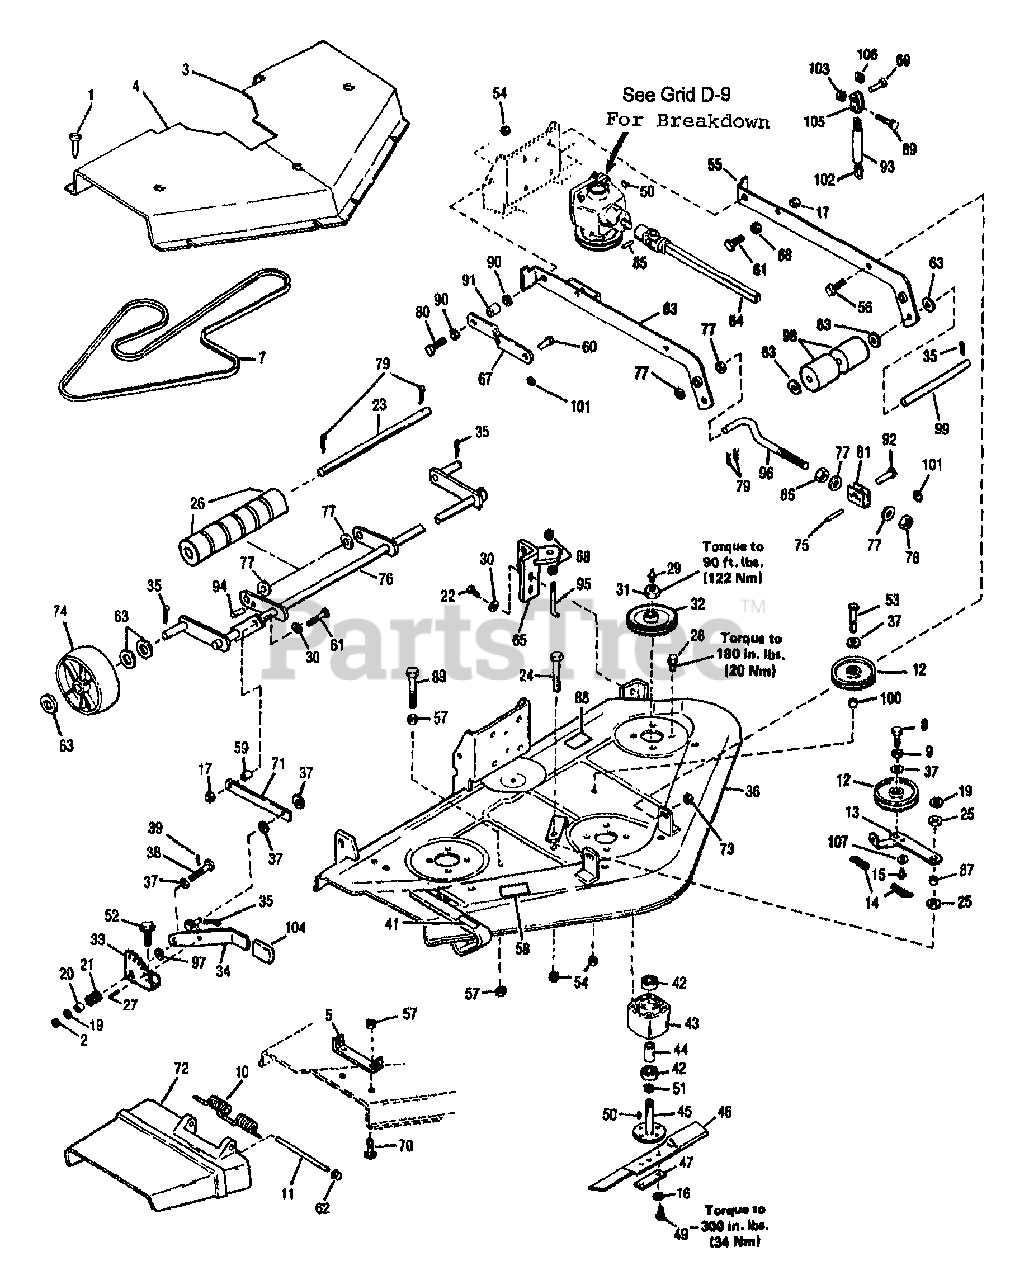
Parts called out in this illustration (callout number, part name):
5	BRKT-HINGE
8	SCR-HH 1/4-20X1.25 G5 ZP
9	WASHER-LK .5
10	SPRING-TORSION
12	PULLEY-IDLER
14	SPRING
15	BUTTON-WEAR
16	WASHER-LK .375 @ DEPL
17	NUT-LOCK 3/8-16
19	WASHER-1.06X.531X.1 ZP
20	SPACER-TUBULAR
21	SPRING
22	SCR-HH 3/8-16X1.0 G5 ZP
23	AXLE-ROLLER
24	SCR-HH 1/2-13X1.5 G5 ZP
25	WASHER
26	ROLLER
27	PIN-.312X.75
28	SCR-HFLK 5/16-18X.75
29	FITTING-GREASE 1/4-28X2.00
30	WASHER-FLAT 3/8 SAE
31	NUT-H/LK
32	SHEAVE-BLADE
34	ASSM-HANDLE
35	PIN-COTTER .120X1.00 ZP
36	BASE-MOWER W/DECALS
37	WASHER-FLAT .88X.5X.06 ZP
38	SCR-HH 1/2-13X2.5 SPECIAL
41	DECAL-CUTTING LINE
42	BEARING-BALL
43	HOUSING-SPINDLE
45	SHAFT
46	BLADE-CUTTER
47	PLATE
49	SCR-HH 3/8-24X1.0 G5 ZP
50	KEY-WOODRUFF .188X.75
51	WASHER-SPECIAL
52	SCR-HFLK 5/16-18X.75 ZP
53	SCR-HH 1/2-13X2.0 G5 ZP
54	NUT-TOP LOCK 1/2-13 ZP
55	ASSM-SUPPORT LH
56	SCR-HFLK 3/8-16X1.00 ZP
57	NUT-TOP/LK 5/16-18 ZP
58	DECAL-OPEI CAUTION
59	SPACER-.625X.39X.343
60	PIN-CLEVIS .625X1.44
61	SCR-HH 3/8-16X1.5 G5 ZP
62	NUT-PUSH 3/8 ZP
63	WASHER-1.305X.649X.098 ZP
65	ASSM-SUPT
68	NUT-HEX/JAM 3/8-16 ZP
69	PIN-CLEVIS
70	BOLT-CARR 5/16-18X.63 ZP
71	LINK-CONNECTING
72	DEFLECTOR-DISCHARGE
73	NUT-HFLK 3/8-16 ZP
74	WHEEL-GAGE
75	PIN-DRIVE
77	WASHER-1.38 X.765X .06 ZP
78	NUT .750-10
79	PIN-COTTER .120X1.25 ZP
80	SCR-HH 1/2-13X1.75 G5 ZP
83	ASSM-SUPT RH
84	ASSM-DRIVESHAFT
85	PIN-DRIVE
86	NUT
87	SLEEVE-BEARING
88	DECAL-BELT DRIVE
89	SCR-HH 5/16-18X1.25 G5ZP
90	WASHER-1/2 FLAT
91	SPACER-TUBULAR
92	PIN-CLEVIS .62X2.50 ZP
93	SLEEVE-CHAIN
94	PIN-ROLL 1/8 X 3/4
95	BOLT-HOOK
97	SPACER-.75X.515X.255
98	ROLLER
99	ROLLER
100	SPACER-TUBULAR
101	RING-COTTER
102	KIT-CHAIN
103	NUT-H/LK 5/16-18
104	GRIP-HANDLE
105	CLEVIS
106	RING-CIRCLE COTTER
107	WASHER-.505X.22X.05
